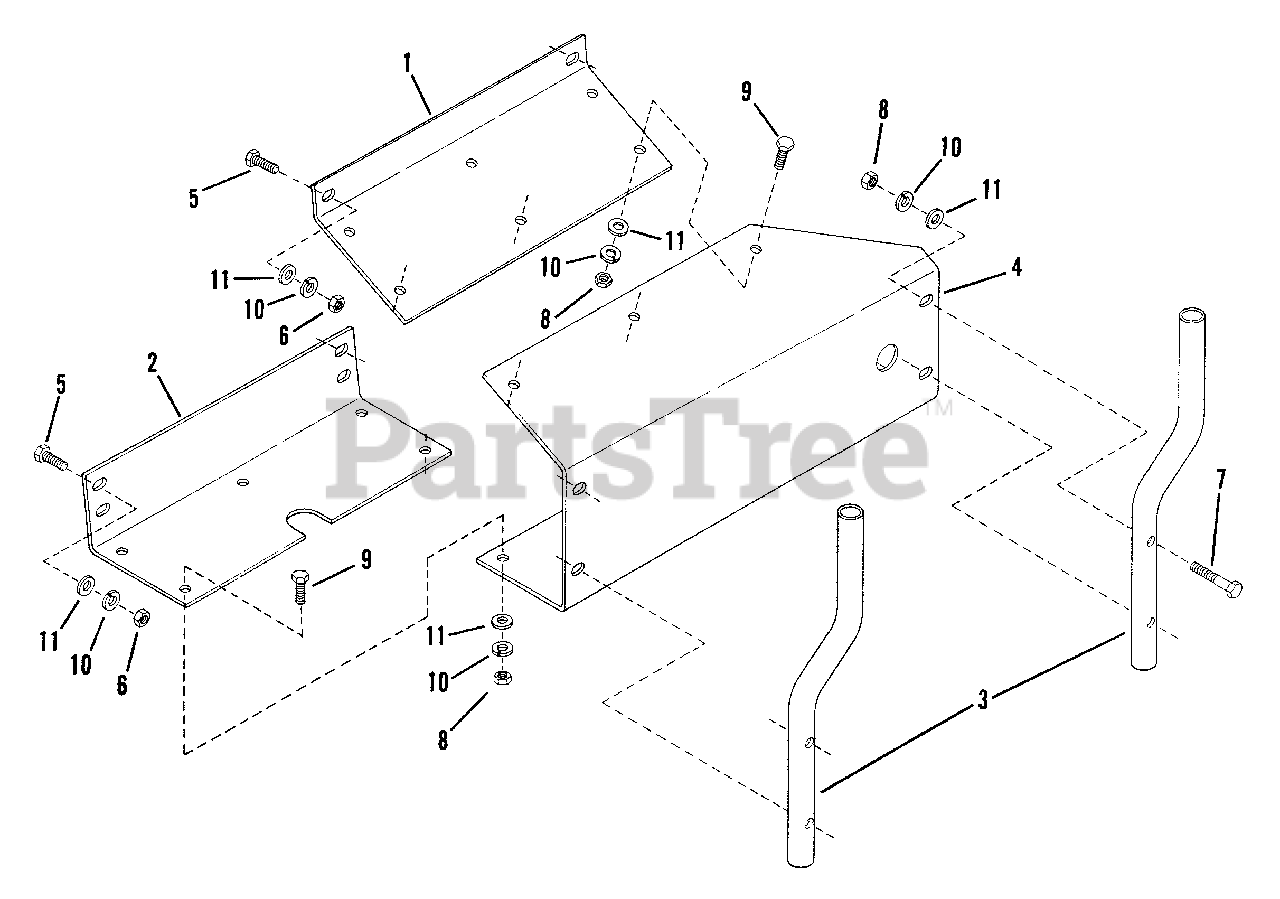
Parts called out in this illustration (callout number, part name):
1	SUPPORT, Upper
2	SUPPORT, Lower
3	TUBE
4	MOUNT
5	SCREW, 5/16-18 x 3/4" Hex Head Cap, Grade 5
6	NUT, 5/16-18 Hex, Grade 5
7	SCREW, 5/16-24 x 1-1/2" Hex Head Cap, Grade 5
8	NUT, 5/16-24 Hex, Grade 5
9	SCREW, 5/16-24 x 3/4" Hex Head Cap
10	WASHER, 5/16 Split Lock
11	WASHER, 5/16 Flat
